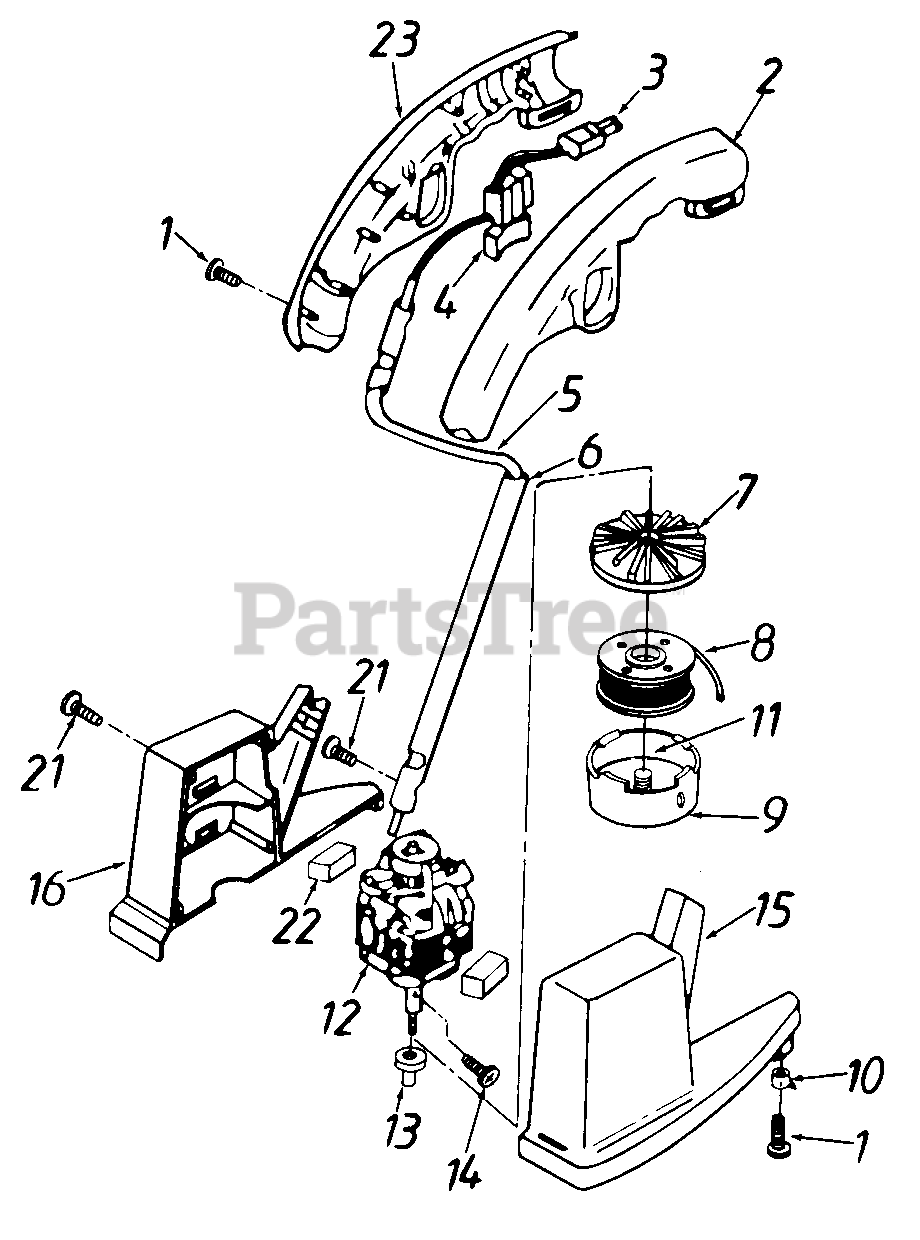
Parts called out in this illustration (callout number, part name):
1	Pan Hd. Scr. #8 x .75" Lg.
2	Handle Trigger-L.H.
3	Cordset-Two Prong
4	Switch Trigger
5	Wire Harness
6	Handle Tube
8	Cartridgew/.065 Line
9	Spool Housing
10	Line Cut Off Blade
11	Spring
12	Motor
13	Shaft Insulator
14	Groove Pin
15	Motor Housing-L.H.
16	Motor Housing-R.H.
21	Screw #8 x 1.5" Lg.
22	Insulator
23	Handle Trigger-R.H.
